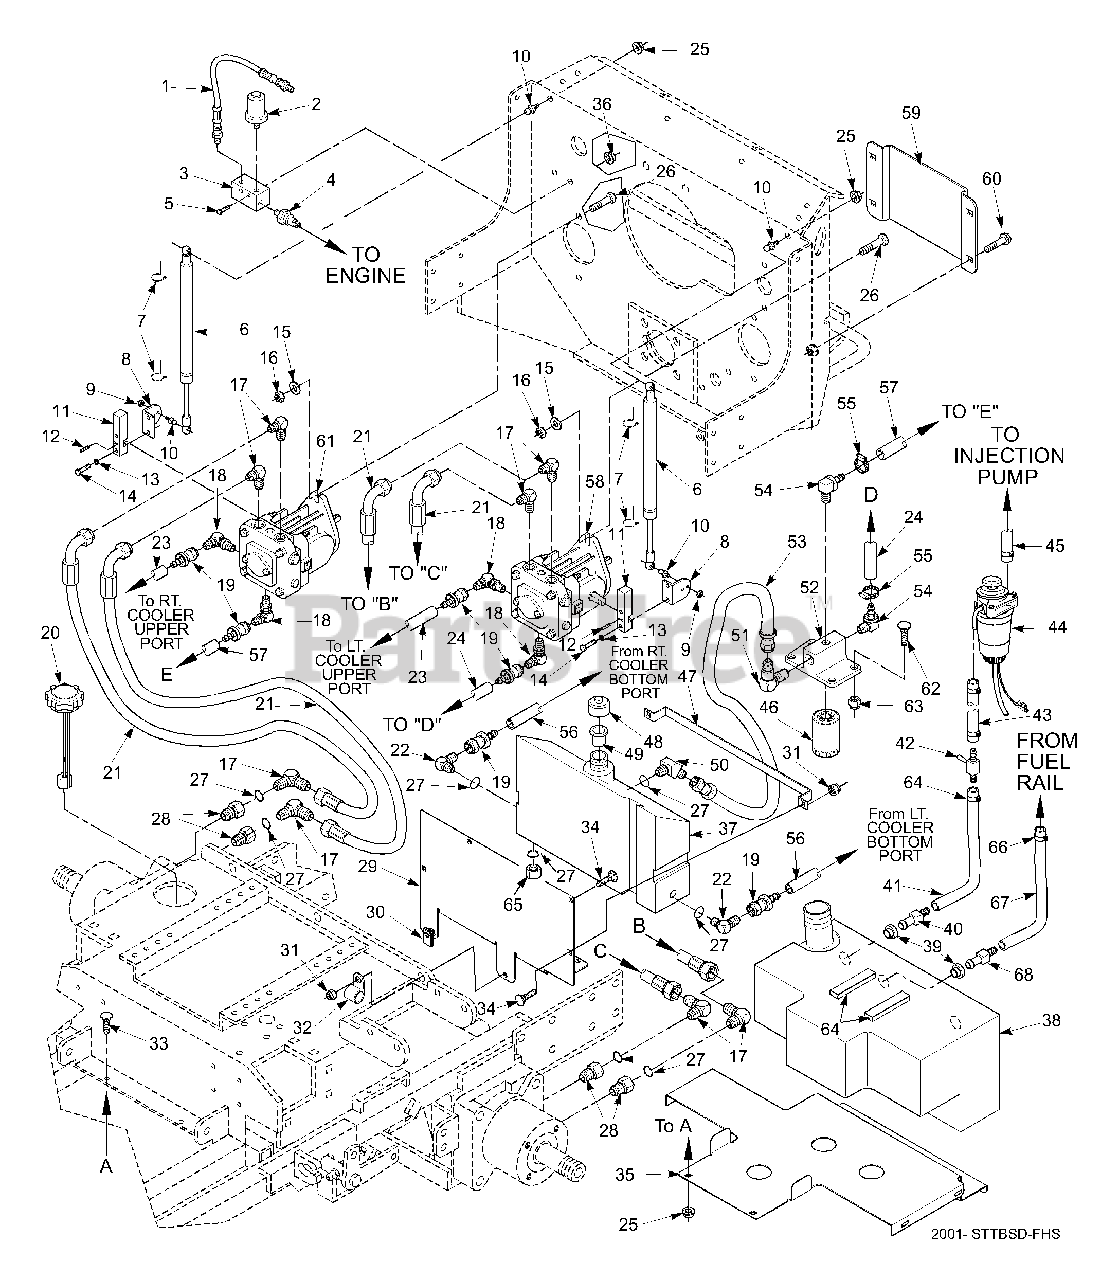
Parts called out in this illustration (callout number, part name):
1	Hose, Oil Pressure Sender
2	Oil Pressure Sender
3	Oil Manifold
4	Switch, Low Oil Pressure
5	Bolt, Hex Head 1/4-20 x 2"
6	Gas Damper
7	Spring Clip
8	Clamp Plate, Pump Control
9	Locknut, 5/16-18 CTR
10	Ball Stud
11	Block, Pump Control
12	Pin, Spring .210 x 1.0"
13	Lockwasher, 1/4 Spring
14	Bolt, Hex Head 1/4-20 x 1.50"
15	Flatwasher, 1/2 (.531 x .062 x .095)
16	Nut, 1/2-13 Elastic Stop
17	Elbow, 90 Degree, 7/8-14 THD
18	Elbow, 90 Degree, 3/4-16 THD
19	Coupling, 3/4-16 THD
20	Cap, Fuel Tank W/Gauge
21	Hose Assembly, Wheel Motor
22	Elbow, 90 Degree, 9/16-18 JIC x 9/16 O-Ring
23	Hose, 3/8" ID. Pushlock - 25.0"
24	Hose, 3/8" ID. Pushlock - 10.25"
25	Nut, 5/16-18 Serrated Flange
26	Bolt, Hex Head 1/4-20 x 2.0"
27	O-Ring
28	Bushing, 7/8-14 JIC x 3/4-16 O-Ring
29	Support Bracket, Hydraulic Tank
30	U-Nut, 1/4-20
31	Nut, Hex Elastic Stop 1/4-20
32	Hose Clamp
33	Bolt, Carriage 5/16-18 x 3/4"
34	Bolt, Carriage 1/4-20 x 1.0"
35	Support Bracket, Fuel Tank
36	Nut, Hex 1/4-20 Serrated Flange
37	Oil Reservior Assembly
38	Fuel Tank Assembly
39	Bushing
40	Hose Fitting
41	Fuel Hose, 1/4" ID. - 10"
42	Valve, Shutoff
43	Fuel Hose, 1/4" ID. - 2"
44	Fuel Filter
45	Fuel Hose To Carb.
46	Oil Filter
47	Strap, Hydraulic Tank
48	Cap, Hydraulic Tank
49	Insert, Filler Neck
50	Elbow, 45 Degree 3/4-16 JIC x 3/4-16 O-Ring
51	Elbow, 45 Degree 1/2 NPT x 3/4 JIC
52	Oil Filter Base
53	Hose Assembly
54	Elbow, 90 Degree-1/4 NPT x 3/8 Hose
55	Clamp, Hose 1/2"
56	Hose, 3/8 ID. Pushlock - 14.50"
57	Hose, 3/8 ID. Pushlock - 38.0"
58	Pump, BDP-21L-305 LH
59	Rear Cover
60	Bolt, Carriage 5/16-18 x .75"
61	Pump, BDP-21L-403 RH
62	Bolt, Carriage 5/16-18 x 1.0"
63	Nut, Hex Elastic Stop 5/16-18
64	Pad, Rubber
65	Plug, 3/4-16" "O" Ring
66	Clamp, 3/16 Hose
67	Hose, 3/16" I.D. -35.0"
68	Hose Fitting, Straight DAPCO
